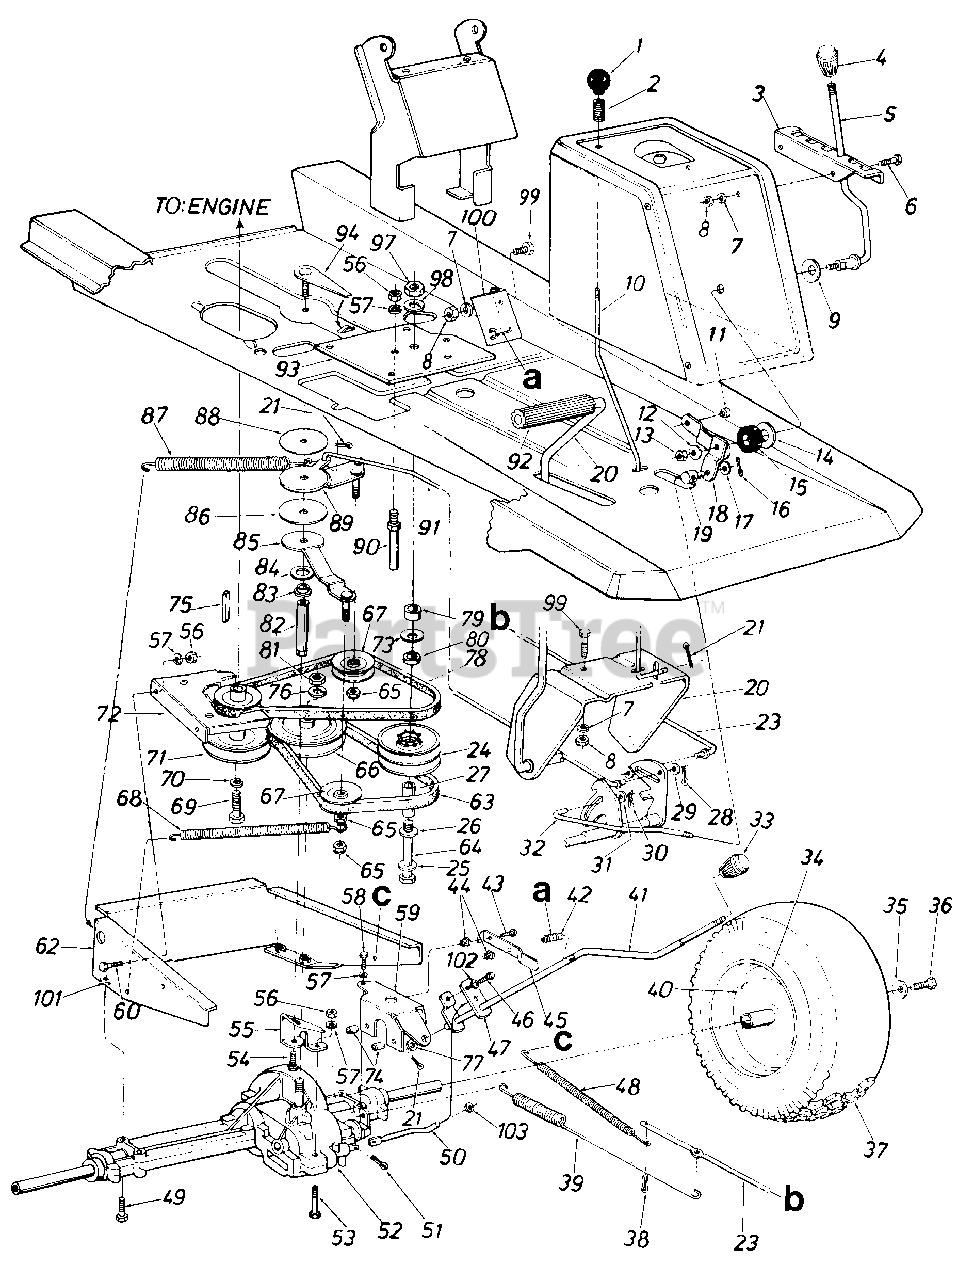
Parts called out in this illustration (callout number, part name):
1	Engine
1	Ball Knob 1/4-20 Thd. 1.25"
2	Compression Spring
4	FI-Wash. .330" I.D. x 1.125" 0.D.
5	Engine Mounting Grommet
5	Speed Control Lever
6	Spacer .315" I.D. x .50" O.D. x .520" Lg.
6	Truss Mach. Scr. 5/16-18 x .75" Lg.*
7	Cable Tie 30.6 Lg.
7	L-Wash. 5/16" I.D.*
8	Hex Wash. Hd. Self-Tap Scr. 3/8-16 x 1.25" Lg.
8	Hex Nut 5/16-18 Thd.*
9	Gas Gauge
9	Bell-Wash. .345" I.D. x .88"
10	Fuel Tank
10	Brake Locking Rod
12	Hose Clamp-.406" Dia.
12	Bell-Wash. .345" I.D. x .08"
13	Hex Cent. L-Nut 5/16-18 Thd.
14	Hex Bolt 5/16-18 x 1.75" Lg.
14	Fl-Wash. .531" I.D. x 1.25" O.D.
15	Hex Bolt 5/16-18 x 2.0" Lg.
15	Rubber Washer
16	Front Console
16	Intern. Cotter Pin 1/2" Dia.
17	Plastite Scr. 5/8 x 1.25"
17	Fl-Wash. .34" I.D. x .68" O.D.
18	Speed Control Lever Brkt. Ass'y.
19	Main Frame
19	Ferrule-Engagement
20	L-Wash. 5/16" I.D.
20	Clutch/Brake Pedal Ass'y.
21	Hex Nut 5/16-18 Thd.
21	Cotter Pin 3/32" Dia. x .75"*
23	Truss Mach. AB-Tap Scr. #10 x .50" Lg.
23	Brake Rod
24	Convoluted Conduit
24	Variable Speed Pulley Ass'y.
25	Washer .635" I.D. x 3.50" O.D.
26	L-Wash. 5/16" I.D.
26	Thrust Brg. 1.25" O.D. x .56" I.D.
27	Hex Nut 5/16-24 Thd.
27	Spacer Sleeve 2.71"
28	Clutch-Brake Pedal Ass'y.
28	Cotter Pin 1/8" Dia. x 1.25"*
29	Hex Bolt 5/16-18 x .75" Lg
29	Fl-Wash. .34" I.D. x .60" O.D.
30	Hex Nut 5/16-18 Thd.
30	Intern. Cot-Pin 5/16" Dia.
31	L-Wash. 5/16" I.D.
31	Fl-Wash. .34" I.D. x .60" O.D.
32	Mounting Brkt. Variable Speed Pulley
32	Speed Control Link
33	L-Wash. 1/4" I.D.
33	Shift Knob
34	Hex Nut 1/4-20 Thd.
35	90ø Elbow Male To Female
35	Bell-Wash. .345" I.D. x .88"
36	Trim Strip 18" Lg.
36	Hex L-Bolt 5/16-24 x .75" Lg.
37	Choke Control
38	Cotter Pin 1/8" Dia. x 1.25"*
39	Extension Spring 17.0" Lg.
40	Air Valve
43	Exhaust Gasket (804)
43	C Sink AB S-Tap Scr. #8 x .50" Lg.
44	Muffler Ass'y. (804)
44	Push-in Nut #10
45	Shld. Bolt (804)
45	Spring Switch
46	FI-Wash. .330" I.D. x 1.25" 0.D.
46	Hex Bolt 1/4-20 x .50" Lg.*
47	Flange Wash. .320" I.D. x .750" O.D.
47	Shift Lever Adjusting Link
48	Ext. Spring 81/4" Lg.
49	Seat Support & Frame Brkt.
49	Hex Bolt 3/16-18 x 2.5"
50	Hex Bolt 5/16-18 x .75" Lg.
50	Shift Rod
51	Intern. Cotter Pin
53	Hex Bolt 1/4-20 x 1.75" Lg.*
54	Hex Bolt 3/8-24 x .75" Lg.*
55	Hex Bolt 1/4-20 x .50" Lg.
56	Engine Cover Ass'y.
57	Throttle Control Box Ass'y.
57	L-Wash. 1/4" I.D.*
58	Self-Tap Mach. Scr. Type "C" 1/4-20 x 1.37" Lg.
59	Shift Lever Support Brkt.
60	Hex Bolt 1/4-20 x l.OO Lg.*
62	Ignition Key
63	Ignition Switch
64	Throttle Control Wire
64	Hex Bolt 3/8-16 x 4.5" Lg.
65	Hex Ins. L-Nut 3/8-24 Thd.
66	5/8 V-Pulley .500" I.D. x 6"
67	Bell-Wash. .345" I.D. x .88" 0.D.
67	V-Belt Idler .38" I.D. x 3.06"
68	Hex Bolt 5/16-18 x .75" Lg.
68	Ext. Spring .50" O.D. x 6.37"
69	Hex Nut 5/16-18 Thd.
69	Hex Bolt 7/16-20 x 1.00" Lg.
70	Hex Self-Tap Scr. 5/16-18 x .75" Lg.
70	L-Wash. 7/16" I.D.
71	L-Wash. 5/16" I.D.
71	Engine Pulley (8 hp)
72	Seat Spring
72	Upper Eng. Belt Guard
73	FI-Wash. .531" I.D. x .930" O.D.
73	Bell-Wash. 1.12 O.D. x .40
74	Spacer .256" I.D. x .50" O.D.
75	Hex Wash. Hd. Tap Scr. 3/8-16 x 3/4" Lg.
75	Sq.-Key 1/4" x 2.00" Lg.
76	L-Wash. 1/2" I.D.
76	L-Wash. 1/2" I.D.*
77	Hex Bolt 1/4-20 x .75" Lg.
77	Fl-Wash. .469" I.D. x .88" O.D.
78	Bell-Wash. .345" I.D. x .88" 0.D.
78	V-Belt
79	Hex Cent. L-Nut 5/16-18 Thd.
79	Spacer 1.00" x .38" O.D.
80	Seat Pivot Bracket
80	Thrust Bearing .56" I.D. x 1.25" O.D.
81	Seat Ass'y. Comp.
81	Hex Nut 1/2-20 Thd.
82	Torque Rod
83	Flange Bearing .378
84	Fl-Wash. .640" I.D. x 1.24"
85	Idler Bracket Ass'y.
86	Thrust Wash. .635" I.D.
87	Extension Spring 7.58" Lg.
88	Thrust Wash. .385" I.D.
89	Idler Bracket Ass'y. For Clutch
90	Belt Guard Pin 1/4" Dia.
91	Clutch Rod
92	Foot Pad
93	Hex Nut 5/16-18 Thd.
93	Mtg. Brkt. Variable Pulley
94	L-Wash. 5/16" I.D.
98	L-Wash. 3/8 Heavy Duty
99	Hex Bolt 5/16-18 x .75" Lg.*
100	Shift Lever Spring Brkt.
101	Hex Sems Nut 5/16-18 Thd.
102	Bell-Wash. .265" I.D. x .75" O.D.
103	Push on Retaining Ring
